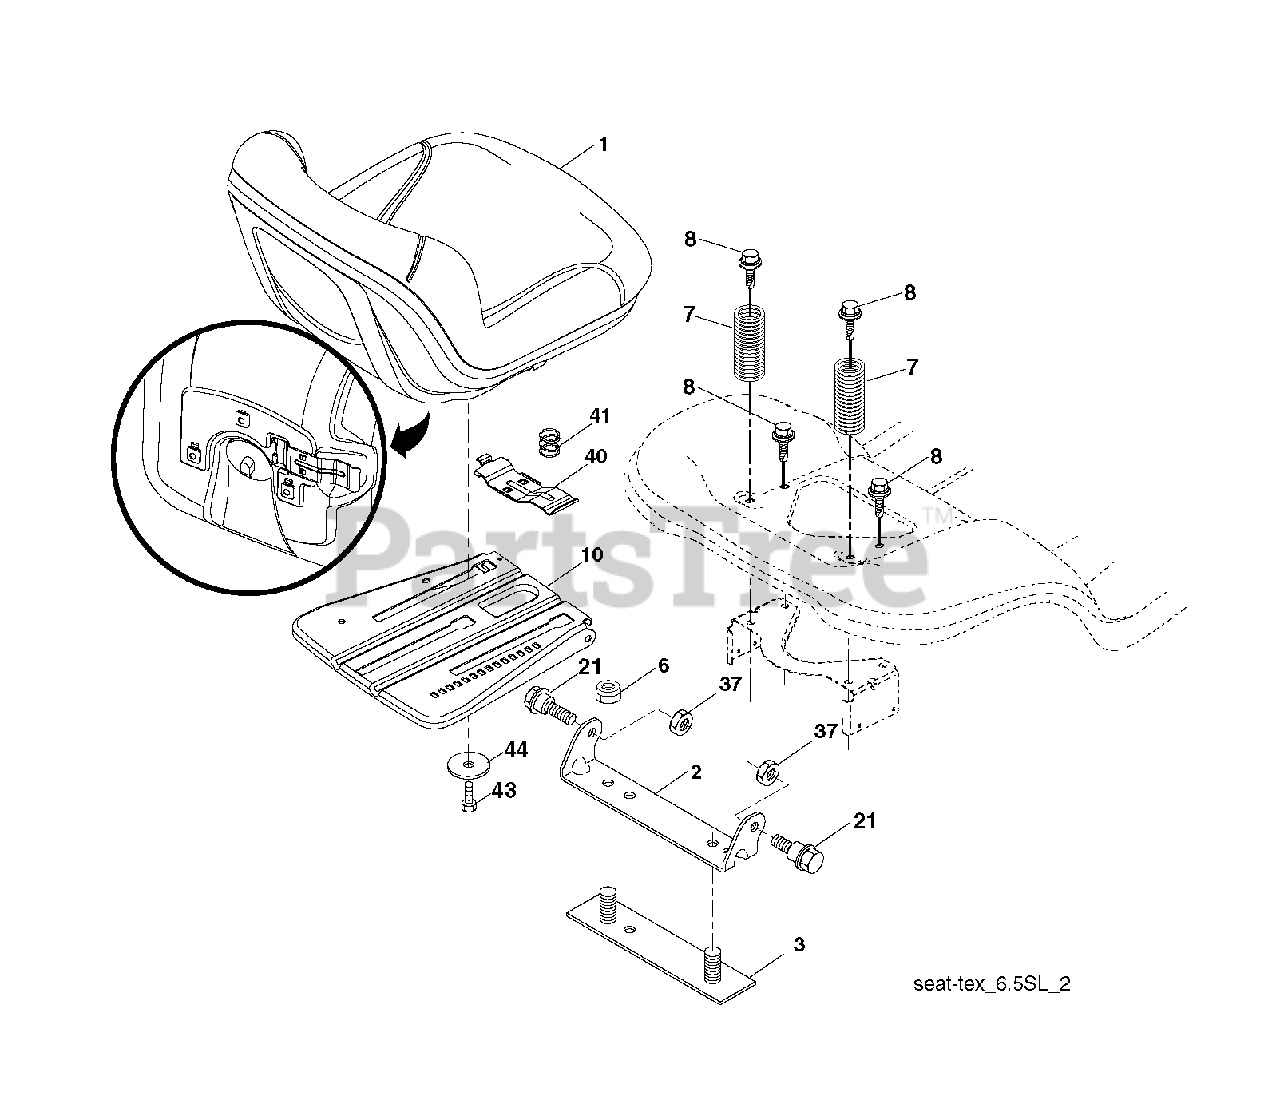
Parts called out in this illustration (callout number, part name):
1	SEAT.TG150.BLK.NLOGO.
2	BRKT.PIVOT.FENDER
6	NUT
7	SPRING COMPRESSION
8	BOLT, 5/16-18 X 1 3/4
10	PAN.ASM.SEAT.3PT
21	BOLT.SHOULDER.5/16-18
37	NUT.71038.31-18.HEX.NYLOCK
40	HANDLE.SLIDE.SEAT.TEX.BLACK
41	SPRING.LATCH.SEAT.TEX
44	WASHER 13/32 X 2-3/8 X 12GA
